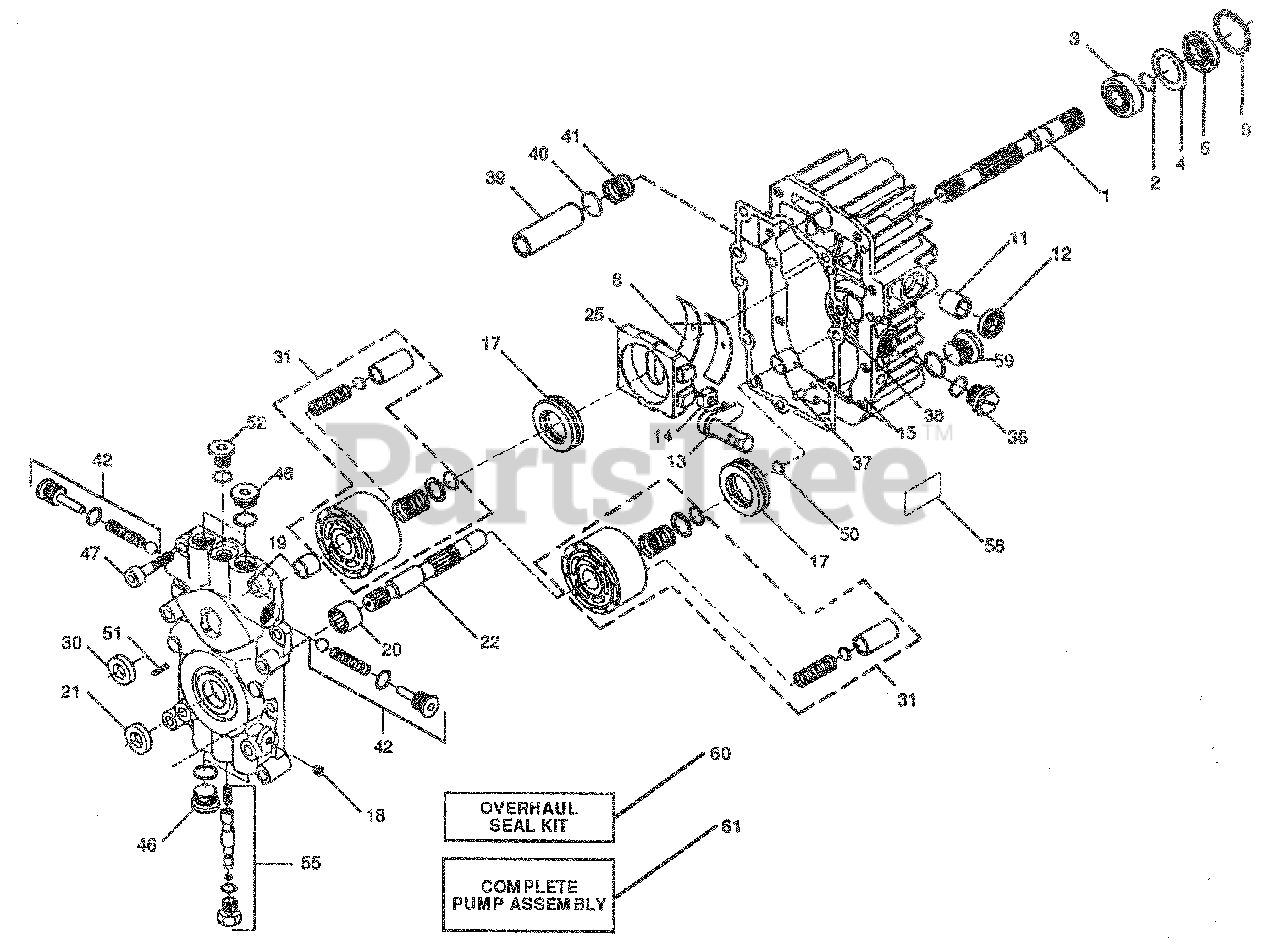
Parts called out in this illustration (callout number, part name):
1	Shaft, Pump
2	Ring, Retaining
3	Bearing, Ball
5	Seal, Lip
6	Ring, Retaining
8	Bearing, Cradle
11	Bearing, Journal
12	Seal, Lip
13	Arm, Trunnion
14	Guide, Slot
15	Housing Kit, Transmission
17	Bearing, Thrust, Ball
18	Plug, Pipe
19	Center Section Kit
20	Bearing, Needle
21	Seal, Lip
22	Shaft, Motor
25	Swashplate, Variable
30	Seal, Lip
31	Block Kit, Cylinder, Pump
36	Plug, Plastic
37	Pin, Stainless, Headless
38	Gasket, Center Section
39	Filter
40	Washer, Thrust
41	Spring, Helical, Compression
42	Check Valve Kit
46	Plug, Stainless, Threaded
47	Screw, Socket Head, Cap
50	Washer, Thrust
51	Pin, Spiral
52	Plug, Stainless, Threaded
55	Bypass Valve Kit
58	Adhesive Label, Bar Coded
59	Plug, Stainless, Threaded
60	Overhaul Seal Kit, BDU-10 Includes; Items marked with *, O-Rings for Check Valves, and Bypass Valve
61	Pump Assembly, Complete
82	Block Kit, Cylinder, Motor
